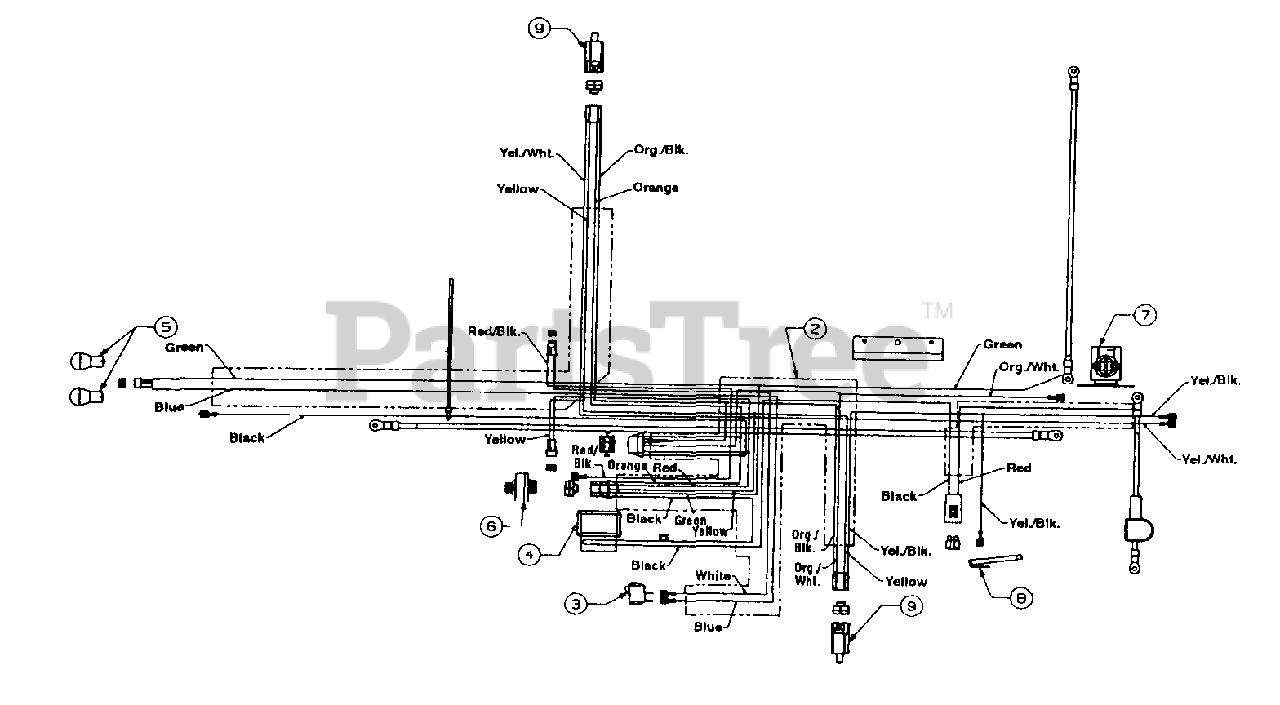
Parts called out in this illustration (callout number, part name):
2	Wire Harness w/Light Switch and Amp
2	Wire Harness w/o Light Switch and Am
3	Light Switch
4	Ammeter
5	Bulb (Headlight)
6	Ignition Switch
7	Solenoid
8	Safety Switch (Reverse)
9	Safety Switch
